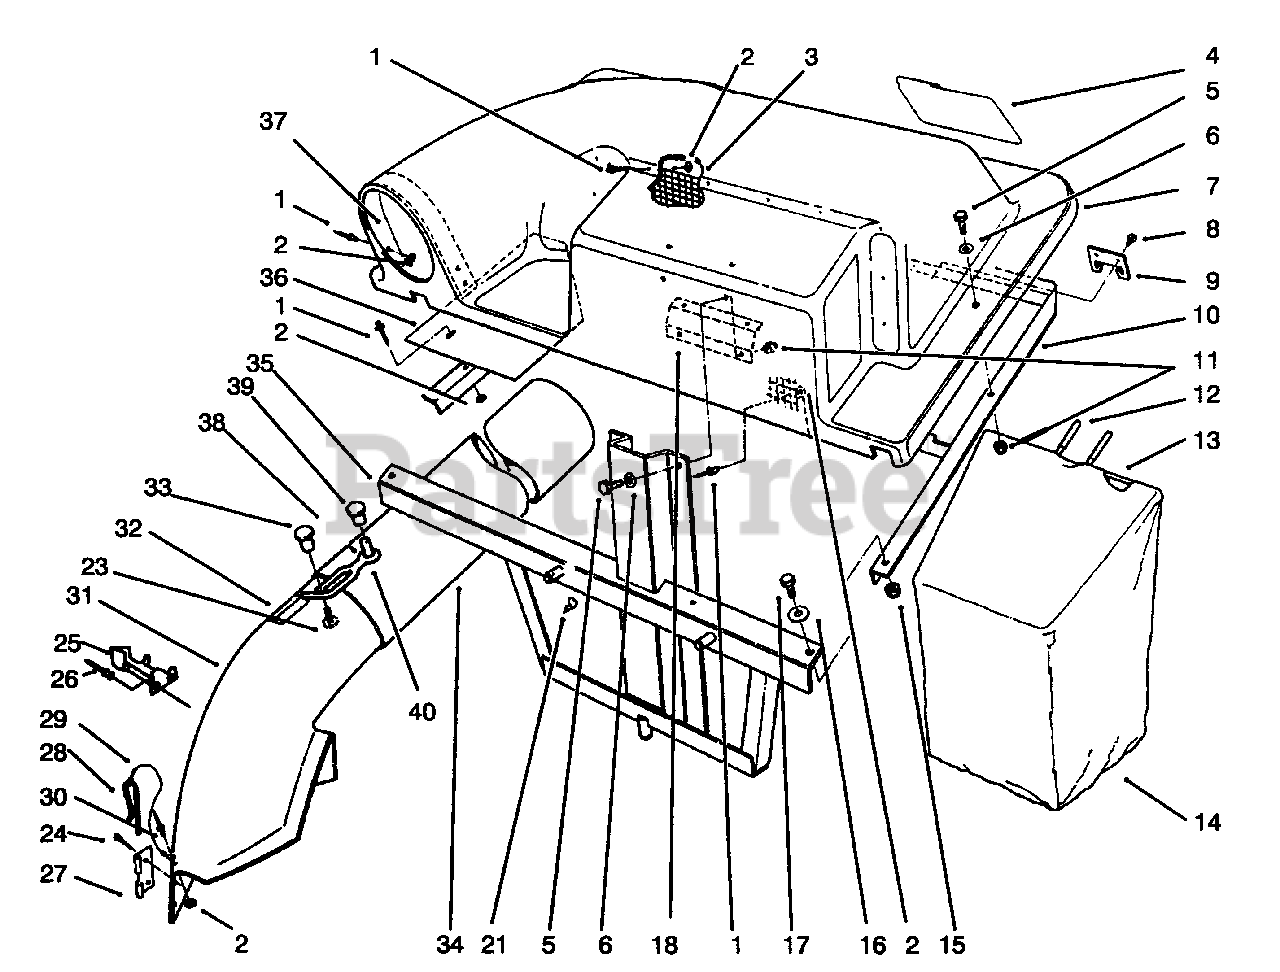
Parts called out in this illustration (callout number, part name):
1	Rivet-Pop
2	Washer-Flat
5	Screw-Cap Hex. Hd.
6	Washer-Flat
8	Screw-Flange, Hex. Hd.
9	Bracket-Frame, Bag
10	Cover-Frame W.A.
11	Nut-Lock
12	Grip-Handle, Bag
13	Frame-Bag
14	Bag-Twin Bagger
15	Nut-Lock
16	Washer-Flat
17	Screw-Cap Hex. Hd.
18	Plate-Backup
21	Pin-Cotter, Hair
24	Rivet-Pop
25	Draw Latch
26	Rivet-Pop
27	Bracket-Mount, Chute
28	Pin-Locking, Chute
30	Rivet-Pop
32	Decal-Danger
34	Tube-Grass Discharge
35	Mount-Frame W.A.
36	Baffle
37	Support-Inlet
39	Fastener-Panel
40	Retainer-Duct
